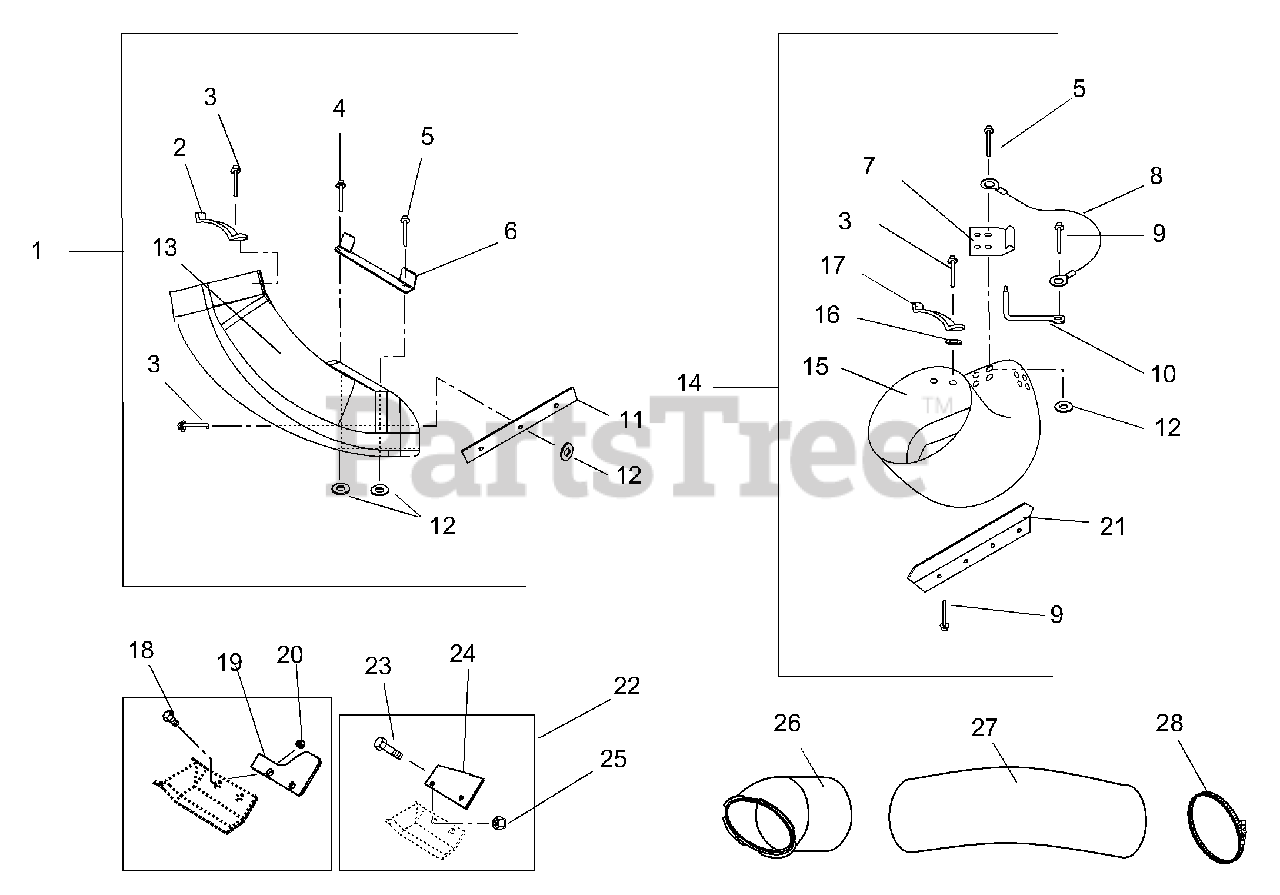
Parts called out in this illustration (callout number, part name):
1	28/32-In. Boot Assembly
2	Tube Retainer
3	Rivet-Pop .187 x .527
4	Rivet-Pop .187 x .277
5	Rivet-Pop .187 x .402
6	Bracket, Bagger Boot Mount
7	Boot Bracket
8	Lanyard
9	Rivet-Tubular .187 x .375 Steel-Aluminum
10	Pull Pin
11	Skirt, Rubber
12	Washer-Flat-Steel .219 x .50 x .049
13	28/32-In. Boot
14	40-In. Boot Assembly
15	40-In. Boot
16	Washer-Flat-Steel .219 x .50 x .049
17	Tube Retainer Clip
18	Bolt-Hex .31-24 x .75 Grade 8
19	28- and 32-Inch Vane
20	Nut-Center-Lock .31-24
21	Extension-Chute
22	40-In. Service Vane Package
23	Bolt-Hex .31-24 x .75 Grade 8
24	40-In. Vane
25	Nut-Center-Lock .31-24
26	Upper Bagger Boot
27	Tube
28	Hose Clamp
